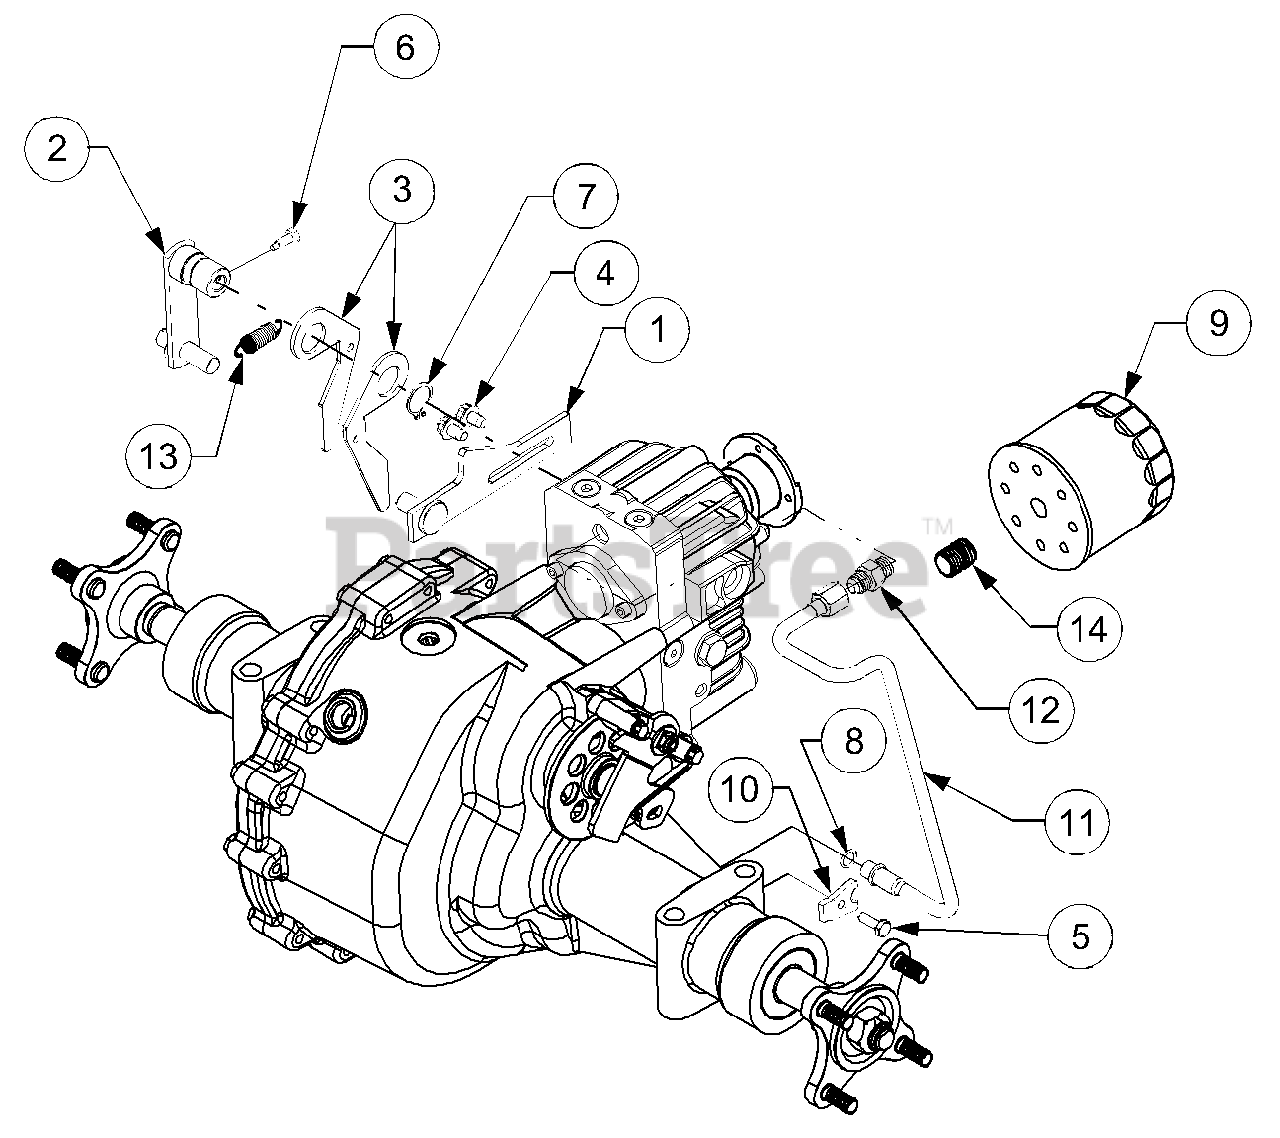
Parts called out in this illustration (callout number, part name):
1	Bracket, Neutral Return
2	Arm Assembly, Control
3	Arm, Neutral
4	Screw, Hex Wash Hd Tapp, 5/16-18 x .50
5	Screw, Hex Cap, 1/4-20 x .75 GR5
6	Screw, Special Hex Cap, 5/16-24 x .625
7	Ring, Snap, .875 Shaft
8	O-Ring, .426 ID x .566 OD x .07
9	Filter, Oil
10	Clamp, Tube, .50
11	Tube, Hydro Pickup
12	Fitting, Hydraulic
13	Spring, Extension
14	Nipple, Oil Filter
